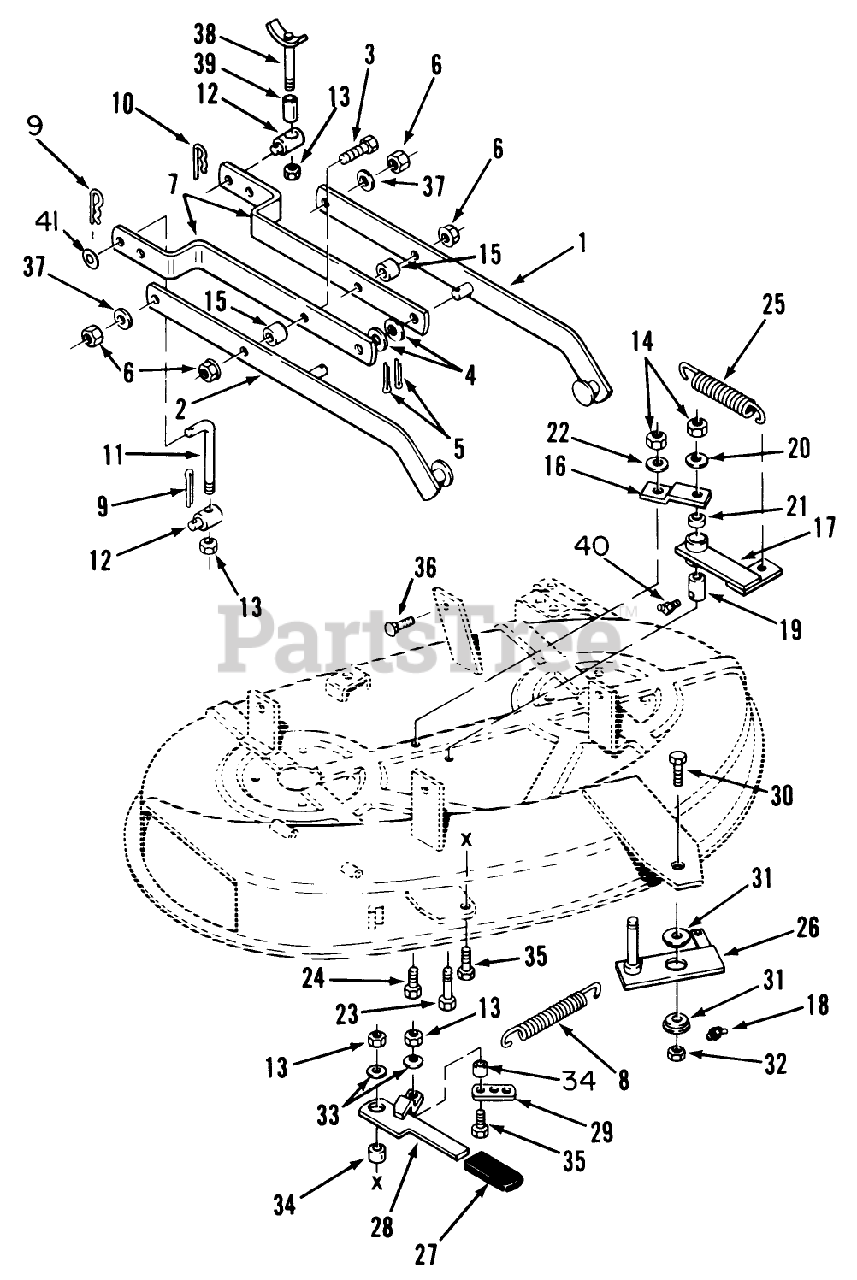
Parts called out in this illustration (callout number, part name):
1	Draft Bar LH
2	Draft Bar RH
3	Bolt
4	WASHER
5	PIN-4
6	LOCKNUT-FLANGE
7	Bar-Leveler
8	Spring
9	Cotter Pin
10	Hairpin
11	ROD-LIFT
12	Trunion
13	NUT
14	Nut
15	SPACER
16	Strap
17	Arm-Idler
19	SPACER-2.0 LG R
21	BUSHING
22	WASHER 5/16 SAE
23	Pin-Cotter
24	Bolt
25	SPRING
26	Countershaft
28	Lever
29	Link
30	Bolt
31	BUSHING
32	Nut
33	WASHER
34	SPACER
35	Bolt
36	Bolt
37	SPACER
38	WLDMT-HANGER ROD
39	SPACER .375 ID X 1.6
40	Grease Zerk
41	WASHER 5/16 SAE
